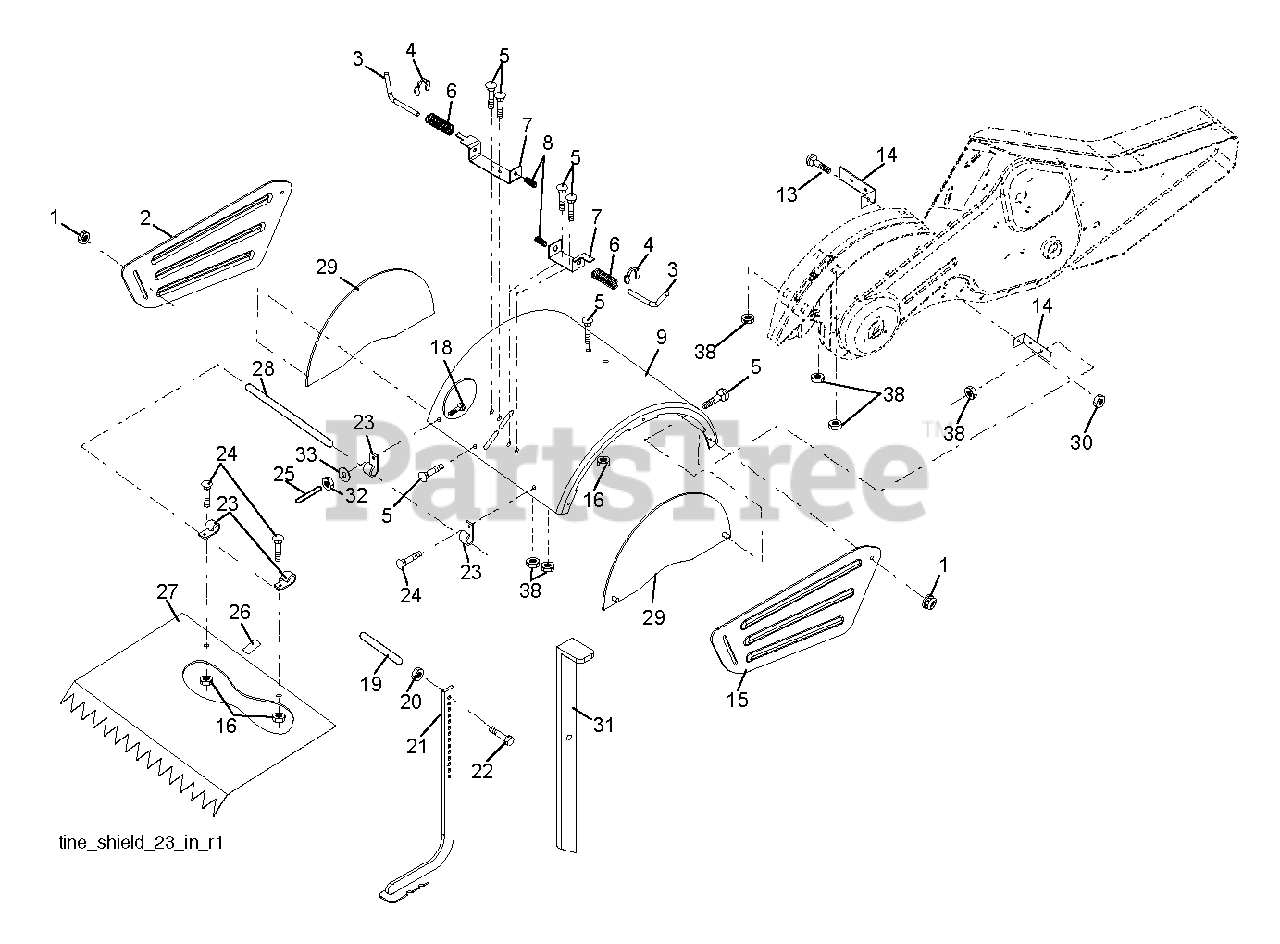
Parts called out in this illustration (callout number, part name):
1	NUT LOCK HEX FLANGE 5/16-18
2	SHIELD.PNT.SIDE.OUTER.LH.ORANG
3	STAKE PIN TI
4	RING, KLIP
5	BOLT, RDHD SQNK 5/16-18 X 3/4
7	BRACKET.LATCH.STAKE.3.20.BLACK
8	SPRING CRT
9	SHIELD.TINE.DRT17.TILLER.ORANG
13	BOLT.CARRIAGE.5/16-18
14	BRACKET.TINE.SHIELD.TILLER
15	SHIELD.SIDE OUTER.RH.ORANGE
16	NUT T
20	NUT.HEX.3/8-16UNC
21	STAKE.DEPTH.16.CRT.BLACK
22	BOLT.375-16
26	PAD IDLER TI
27	SHIELD.LEVELING.17".ORANGE
28	PIN.HINGE.TILLER
29	SHIELD.TINE.SIDE.ORANGE.TILLER
30	LOCKNUT-FLANGE 5/16-18
31	STAKE DRAG
32	NUT
33	LOCKWASHER
38	NUT
